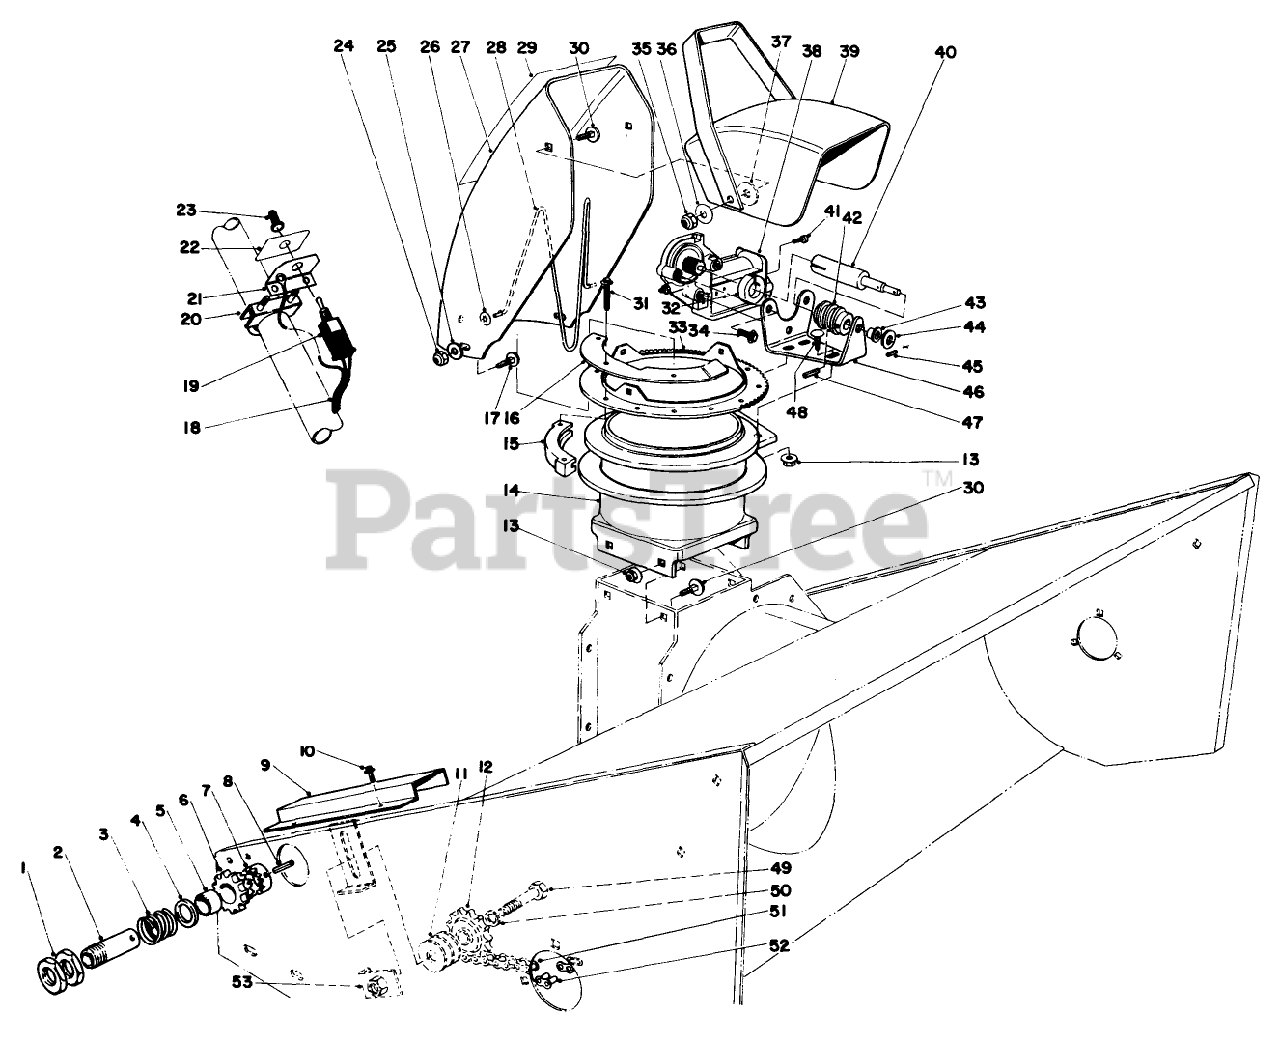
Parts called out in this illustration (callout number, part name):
1	THIN NUT
2	CLUTCH SLEEVE
3	COMP. SPRING
4	Spacer
5	BUSHING
6	CLUTCH SPROCKET
7	CLUTCH COLLAR
8	PIN-ROLL
9	Chain Cover
10	SCREW-HWHTF
11	WASHER-FLAT
12	IDLER SPRKT (60016)
13	NUT-HHF, WHIZ
14	Chute Transition
15	RETAINER-CHUTE
16	Stop-Chute Rotator
17	SCREW-CARR
18	WIRE HARNESS
19	Toggle Switch (Incl. Ref. #23)
20	CLAMP
21	Toggle Switch Mount
22	DECAL
23	BOOT-SWITCH
24	NUT-LOCK, NI
25	WASHER-PLAIN
26	NUT-PUSH
27	Upper Chute
28	WIRE-CHUTE
29	Decal-Warning
30	SCREW-CARR
31	SCREW-SPECIAL
32	SPLIT COLLAR
33	RING - CHUTE SWIVEL
34	SCREW-HHF
35	NUT-LOCK, CONE
36	WASHER-BELLEVILLE
37	WASHER-RUBBER
38	ELEC GEAR MOTOR
39	Deflector
40	WORM GEAR SHAFT
41	SCREW-HSH
42	GEAR-WORM, CHUTE
43	FLANGE BSHG #FF-310-3
44	WASHER-FLAT
45	3/32 X 9/16 ROLL PIN
46	Motor Mount
47	PIN-SPRING
48	BOLT-CARR
49	SCREW-HH
50	WASHER-LOCK
51	ROLLER CHAIN (60023)
52	LINK-CHAIN
53	NUT PLATE WA (60095)
